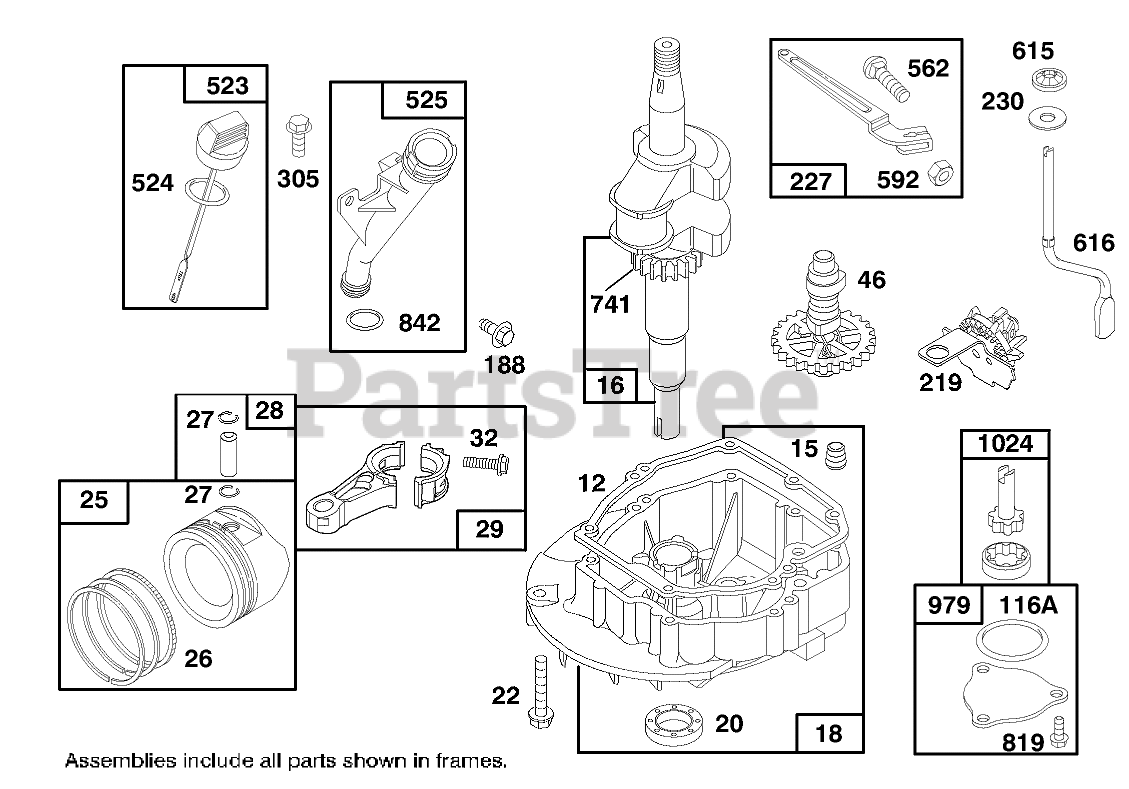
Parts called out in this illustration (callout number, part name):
12	ENGINE BASE GASKET
15	PIPE PLUG
16	Crankshaft
18	ENGINE SUMP
20	SEAL-OIL
22	SCREW - ENGINE BASE
25	STD PISTON ASSEMBLY
26	STD RING SET
27	PISTON PIN LOCK
28	PIN ASM - PISTON
29	CONNECTING ROD
32	SCREW - CONNECTING ROD
46	CAM GEAR
116A	O RING SEAL
188	Screw-Cap
219	GOVERNOR/OIL SLINGER
227	GOVERNOR LEVER ASSEMBLY
230	WASHER
305	SCREW - HEX HEAD
523	DIPSTICK-OIL
524	O-RING
525	OIL FILLER TUBE
562	GOVERNOR LEVER BOLT
592	HEX NUT
615	FASTENER
616	GOVERNOR CRANK
741	TIMING GEAR
819	SCREW - SEM
842	O-RING
979	OIL PUMP COVER
1024	OIL PUMP
